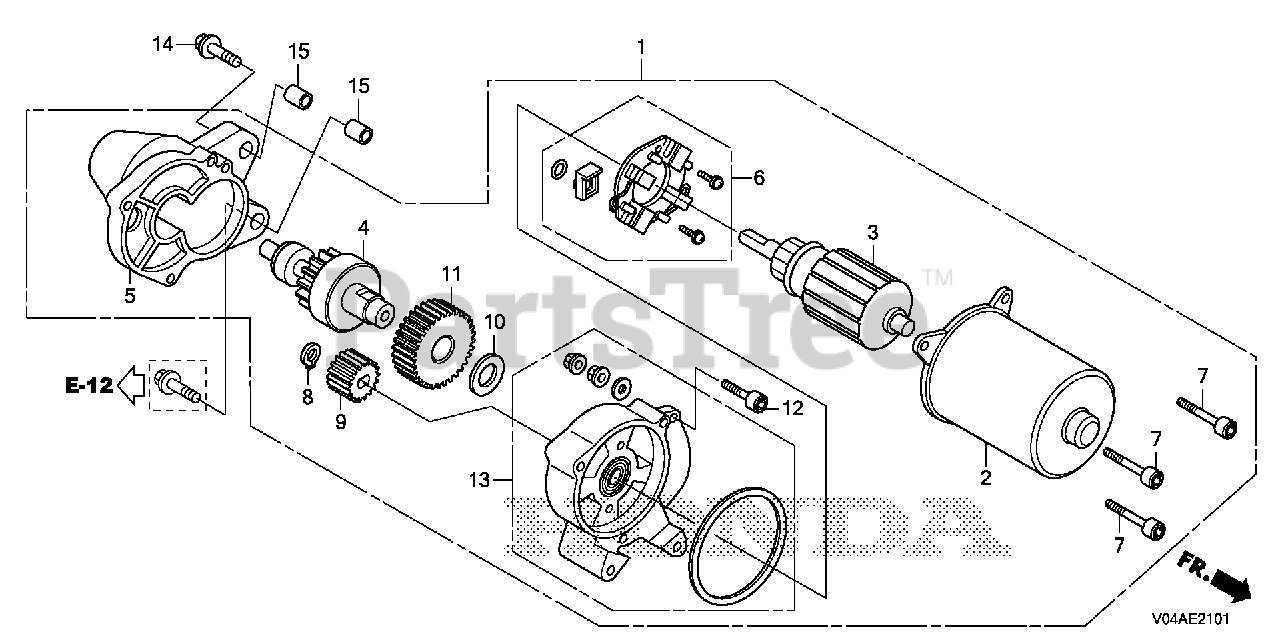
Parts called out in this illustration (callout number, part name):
1	STARTER MOTOR UNIT
2	HOUSING ASSY.
3	ARMATURE ASSY.
4	GEAR ASSY., DRIVE
5	CONE ASSY., NOSE
6	BOARD ASSY., BRUSH
8	RING, RETAINER
13	BRACKET ASSY.
14	BOLT, FLANGE (6X32)
15	PIN A, DOWEL (8X10)
